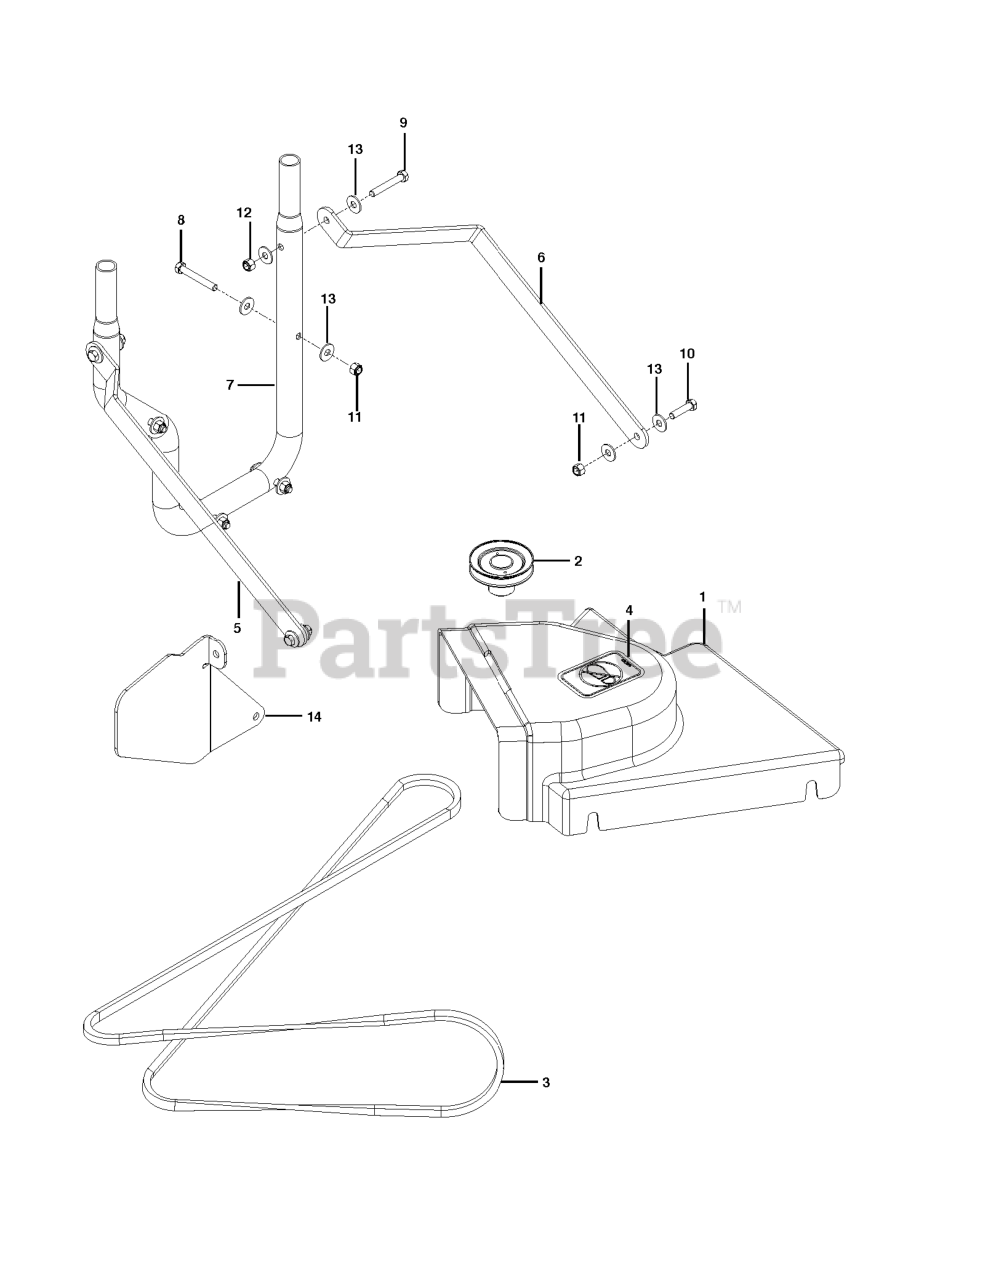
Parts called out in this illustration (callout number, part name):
1	SHIELD, BELT, 52"
2	PULLEY, 52"
3	BELT, 48/52"
4	DECAL, NO STEP
7	MOUNT.TUBE.COLLECTIONS
9	HCS 5/16-18X2
10	HCS 5/16C X 1 1/4
11	NUT 5/16 NYLOC
12	NUT 3/8-16 NYLOC
13	WASHER 5/16 FLAT
14	GUARD, EXHAUST, BLK
